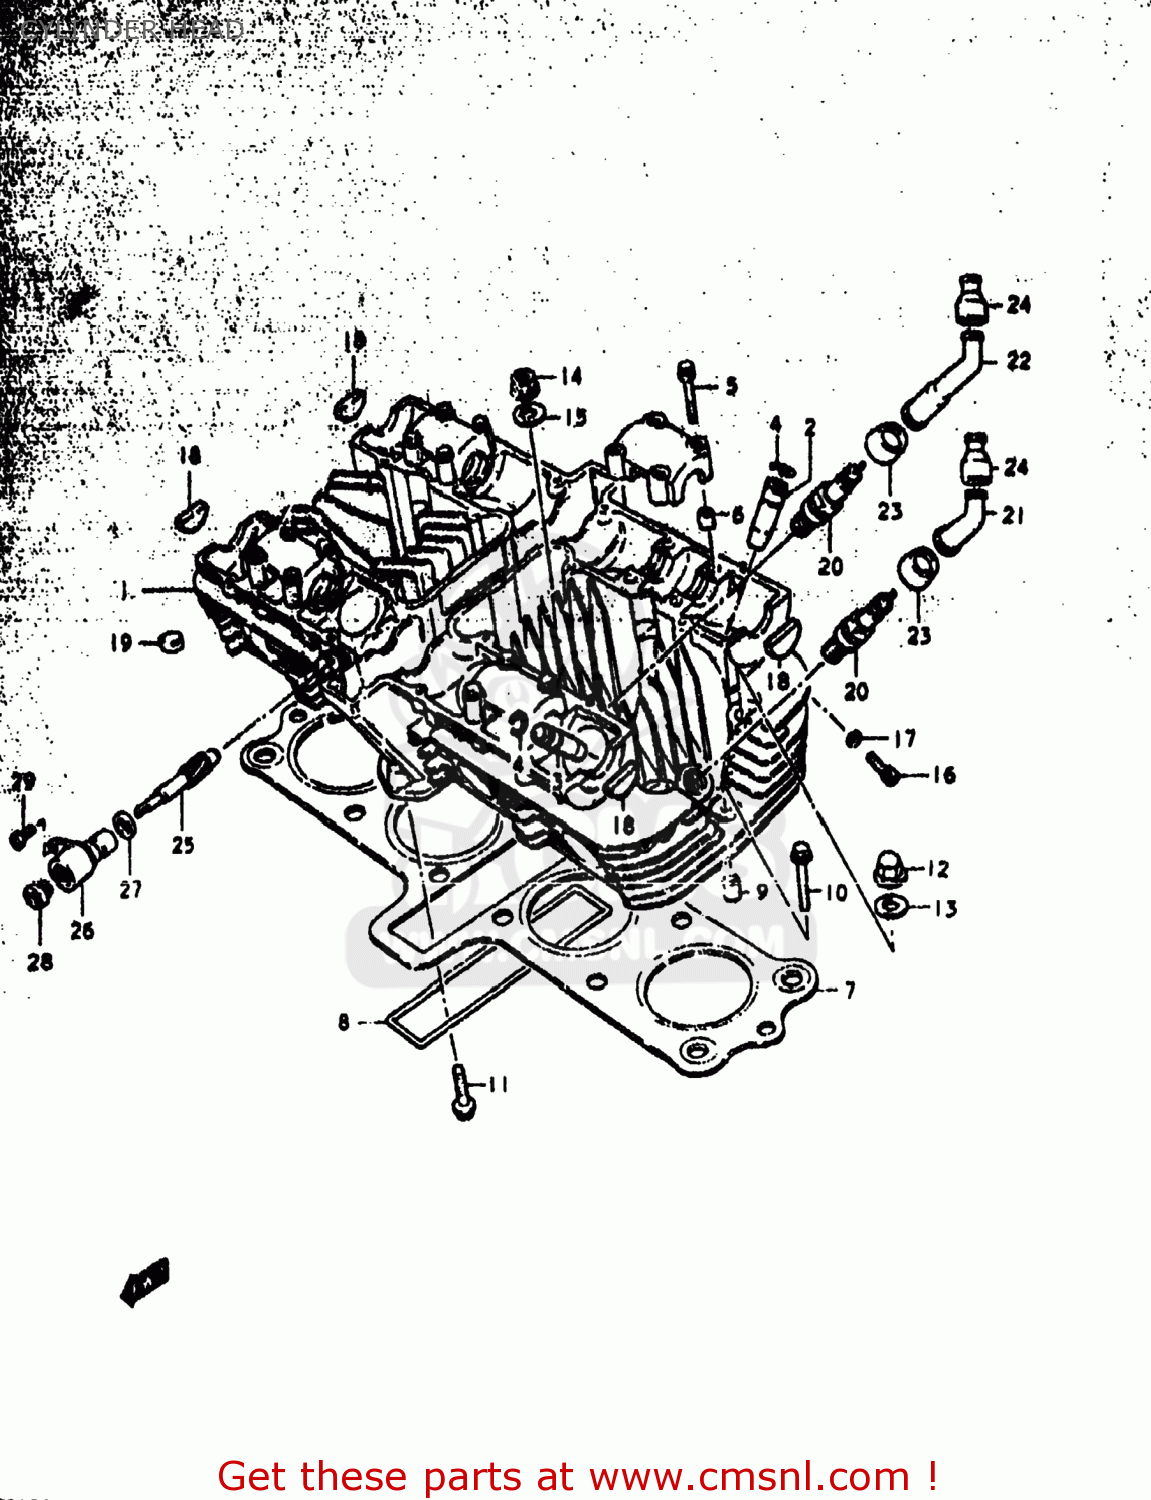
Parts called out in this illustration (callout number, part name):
1	HEAD ASSEMBLY,CYLINDER
2	GUIDE,VALVE
3	GUIDE,VALVE
4	RING,SNAP
5	BOLT(6X39)
6	PIN(6.2X8X11)
7	GASKET,CYLINDER HEAD (MCA)
8	O RING(D:3,ID:26X157)
9	PIN
10	BOLT,UNDER
11	BOLT
12	NUT
13	GASKET(10.5X22X2) (NAS)
14	NUT
15	WASHER(10.5X22X2.3)
16	BOLT
17	GASKET(5.3X9.3X1.2) (NAS)
18	PLUG
19	PAD
20	PLUG,SPARK
21	CAP,SPARK PLUG
22	CAP ASSY,SPARK PLUG
23	SEAL,SPARK PLUG
24	SEAL,SPARK PLU
25	GEAR,TACHOMETER DRIVEN
26	SLEEVE,TACHOMETER DRIVE GEAR
27	SEAL,TACHOMETER DRIVEN
28	SEAL
29	SCREW(5X12)
